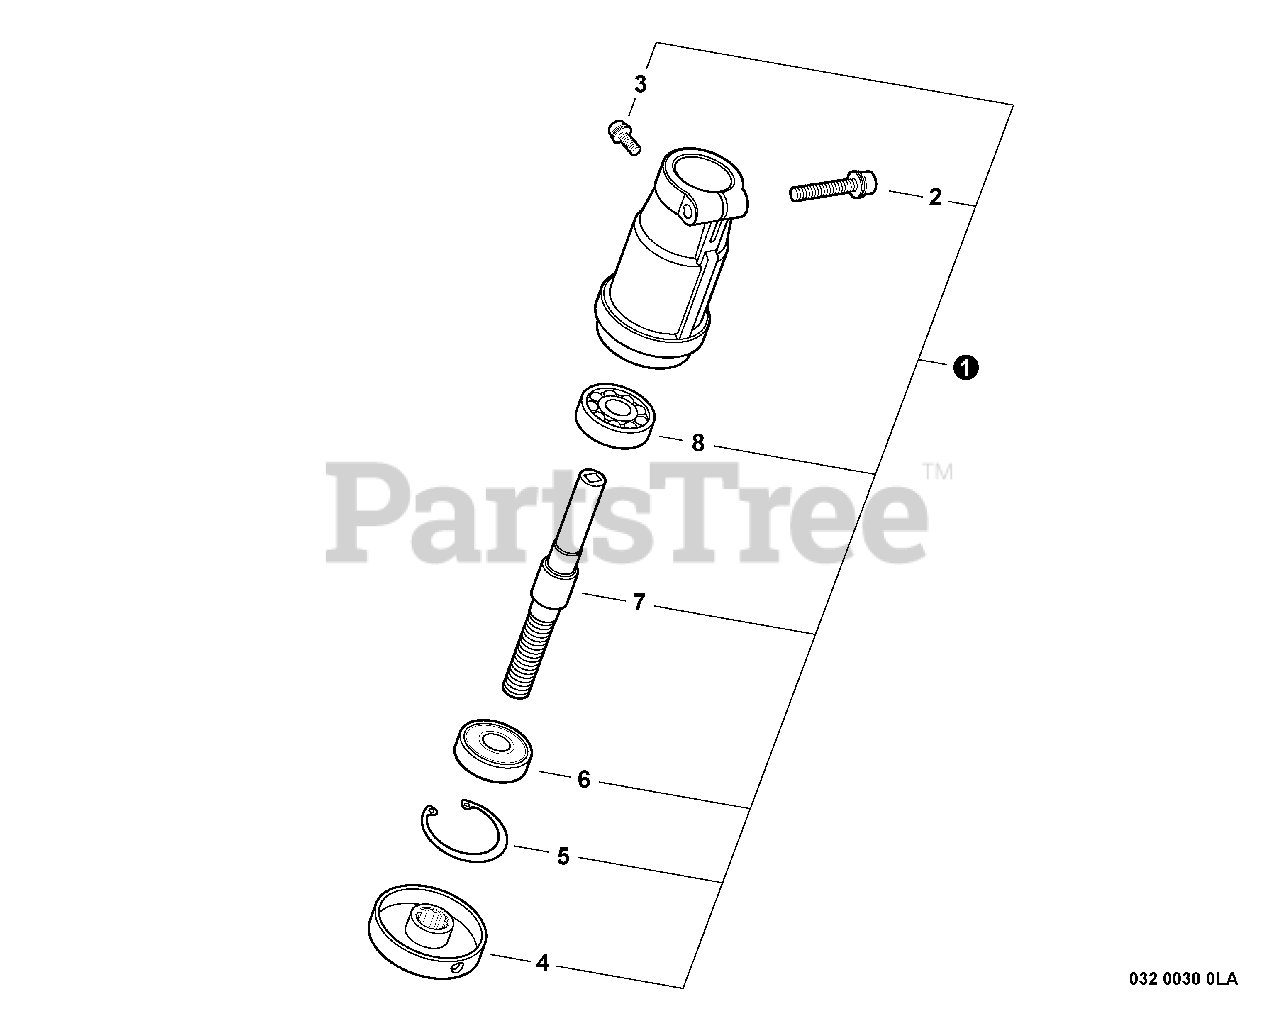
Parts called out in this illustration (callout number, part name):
1	GEAR CASE ASSY
2	BOLT 5×25
3	SCREW 4×10
4	PLATE, ADAPTOR 3/8"-24UNF
5	E-RING 30
6	BEARING, BALL 6200
7	SHAFT, GEAR
8	BEARING, BALL 6200
